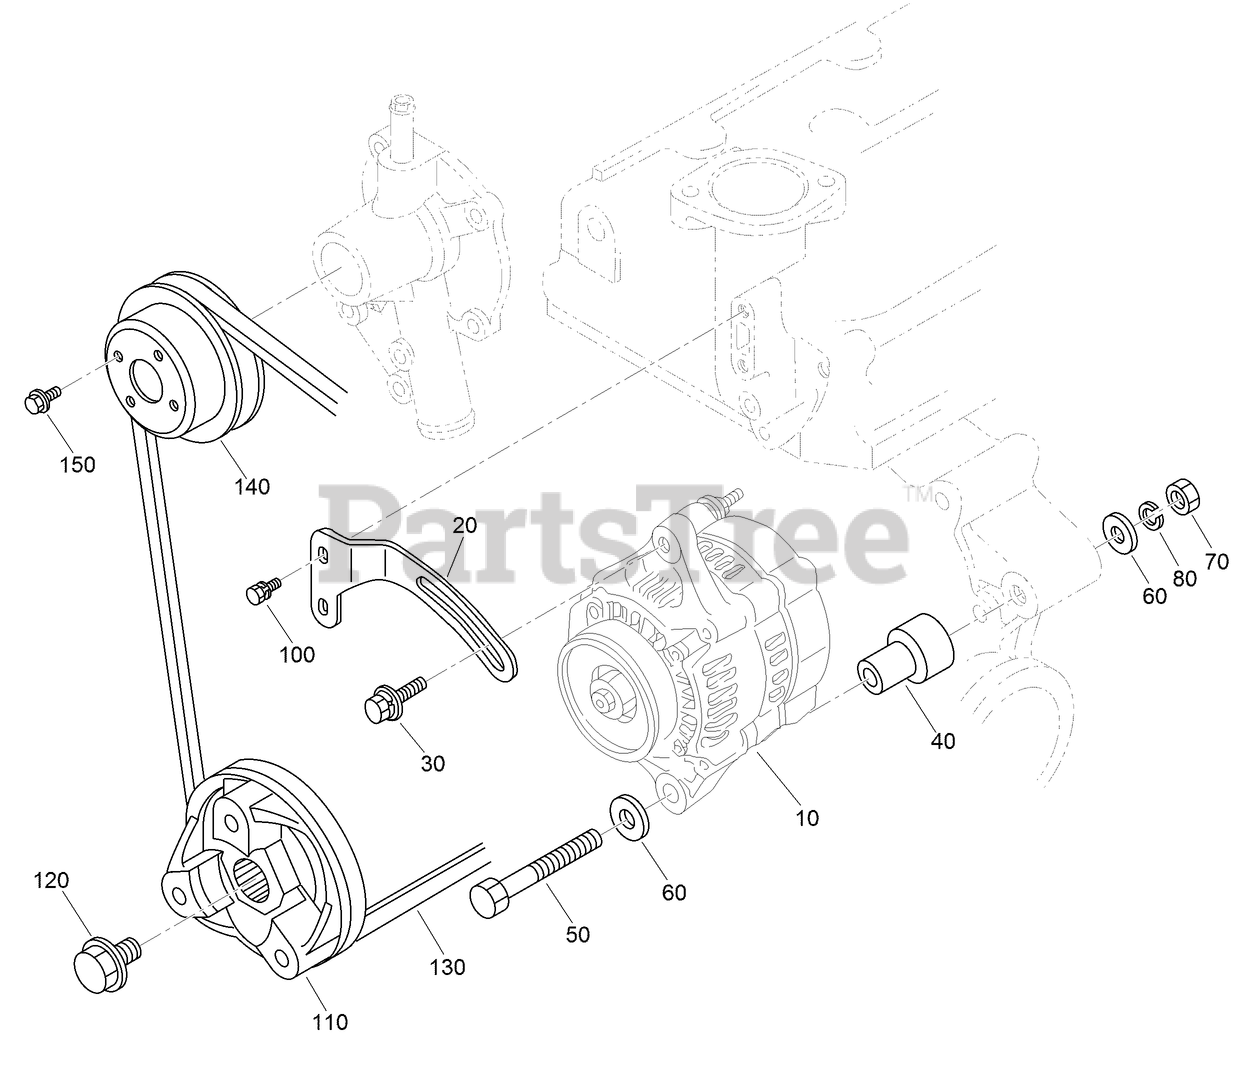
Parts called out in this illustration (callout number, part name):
10	ALTERNATOR
20	STAY-ALTERNATOR
40	COLLAR
60	WASHER-PLAIN
80	WASHER-SPRING, LOCK
110	PULLEY-DRIVE, FAN
130	V-BELT
140	PULLEY-FAN
150	BOLT-FLANGE
